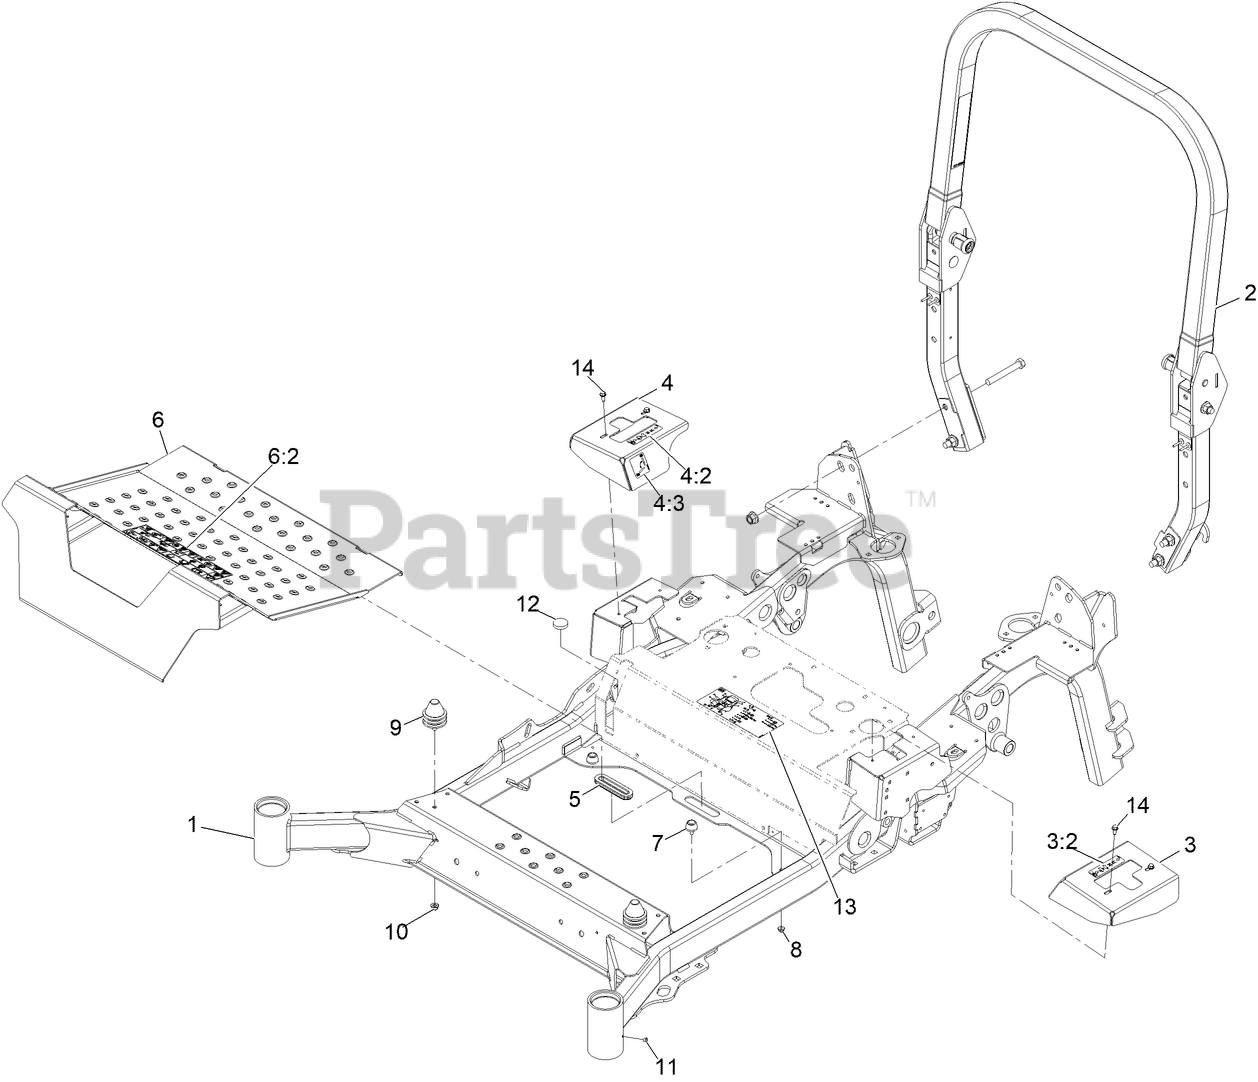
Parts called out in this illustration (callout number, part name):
1	Mainframe ASM, 60
2	ROPS ASM
3	COVER-MOTION CONTROL, LH
3:2	DECAL-CONTROL, MOTION
4	COVER-MOTION CONTROL, RH
4:2	DECAL-CONTROL, MOTION
4:3	DECAL-PARK BRAKE, CE
5	GROMMET-RUBBER
6	PAN-FLOOR
6:2	DECAL-DANGER
7	BUMPER-RUBBER
9	ISOLATOR
10	NUT-HF, NI
12	BUMPER-PUSH-IN, RUBBER
13	DECAL-SERVICE AID
14	SCREW-HWH
